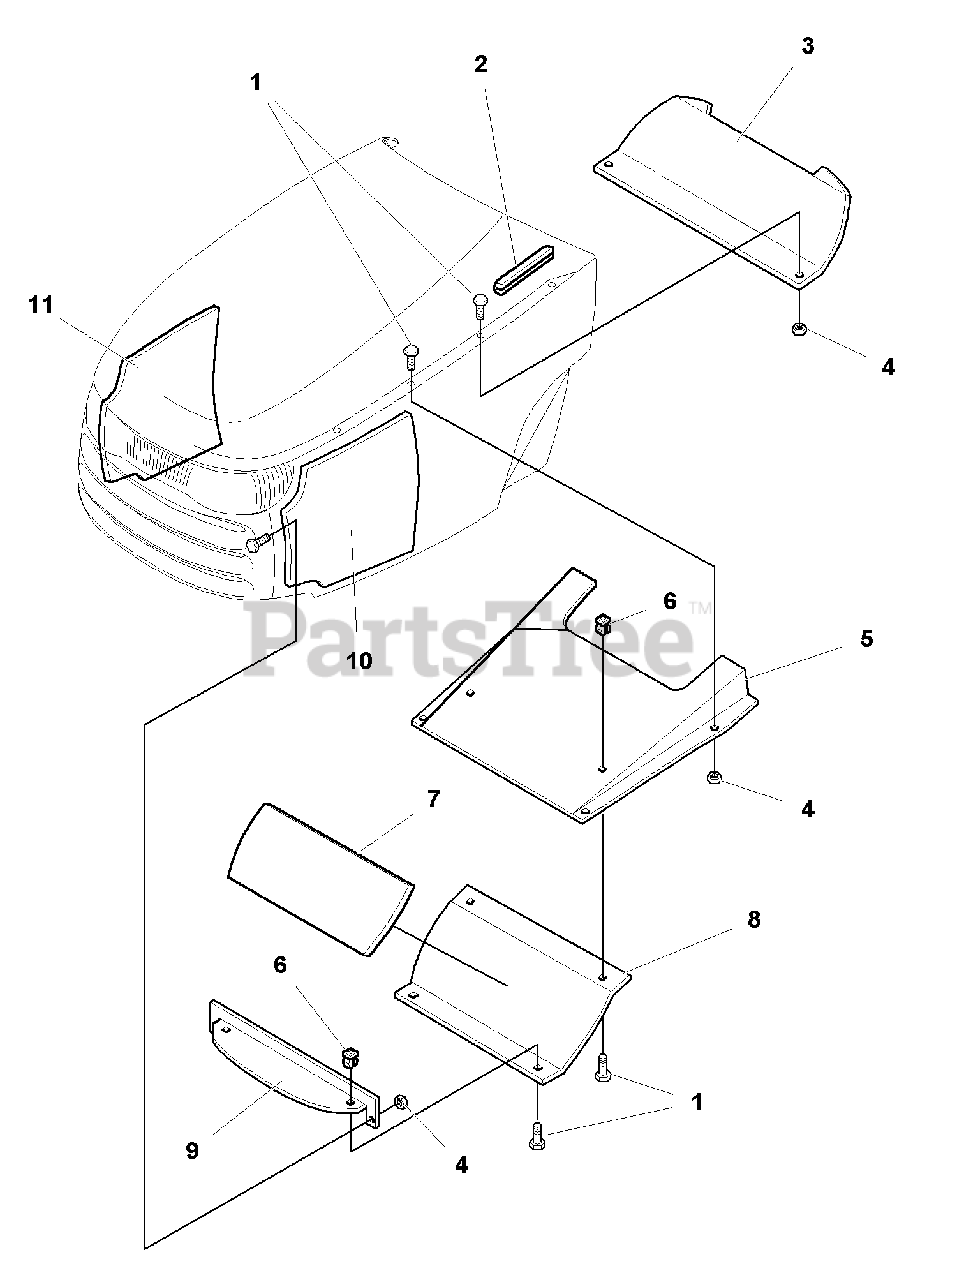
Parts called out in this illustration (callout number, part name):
1	CAPSCREW, Hex Head Whizlock, 1/4-20 x 5/8
2	MOULDING, 5"
3	SHIELD, Hood (Air Cooled Models Only)
4	NUT, Hex Whizlock, 1/4-20
5	SHIELD, Inner Hood
6	NUT, Retainer, 1/4-20
7	INSULATION, Headlight
8	PLATE, Headlight Shield
9	AIR DEFLECTOR, Headlight
10	INSULATION, LH Hood
11	INSULATION, RH Hood
